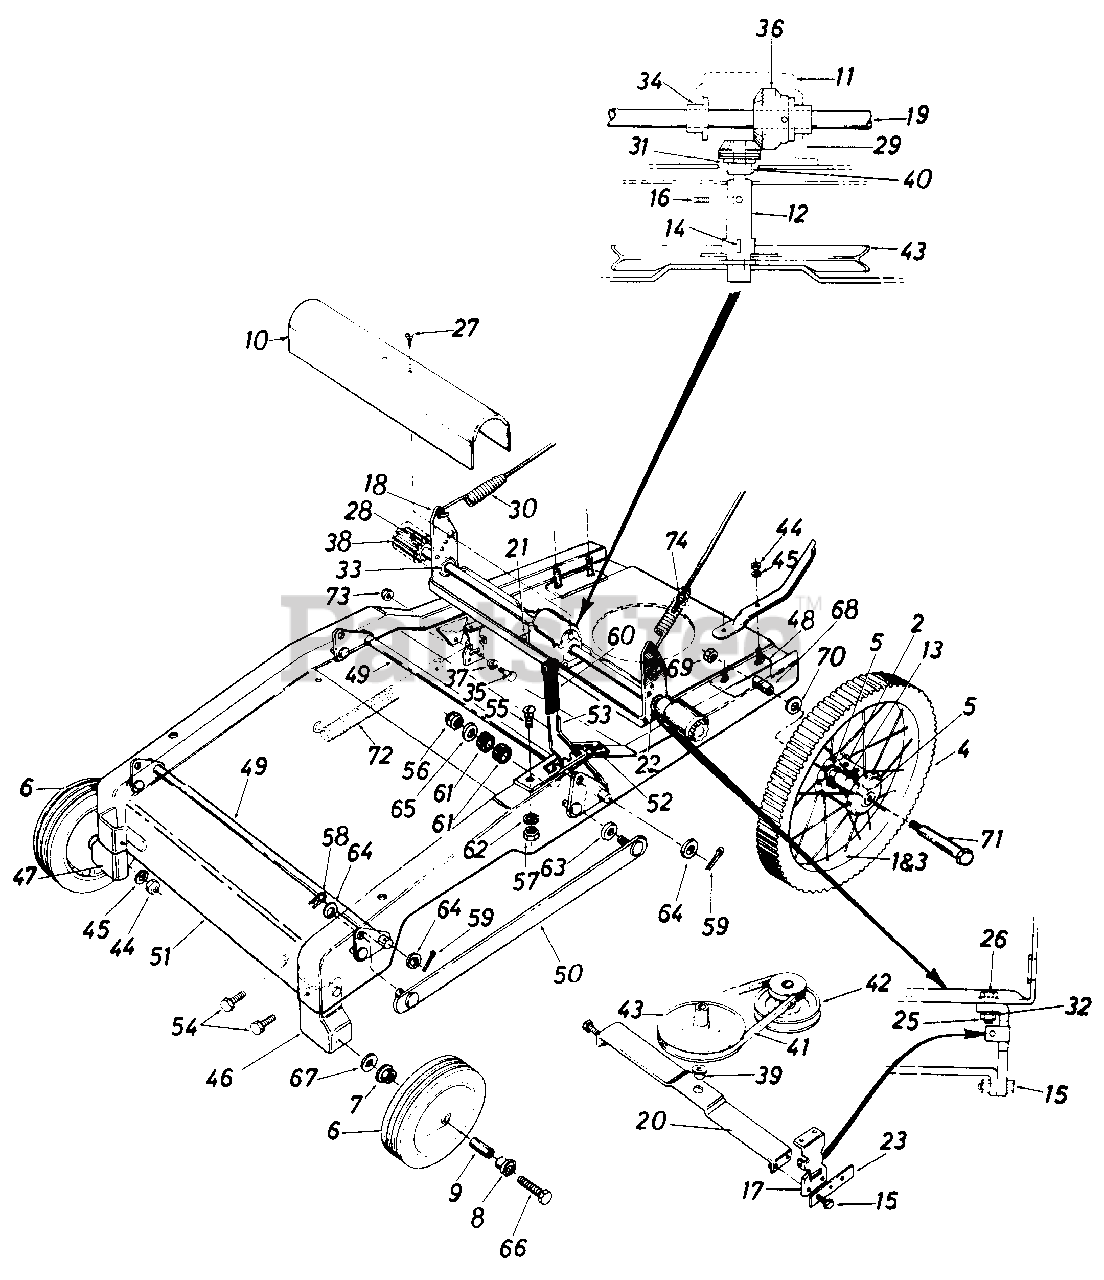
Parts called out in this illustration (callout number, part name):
1	16" Wheel Ass'y. Comp.-Rear
3	Rear Wheel Rim Only
4	Rear Wheel Tire Only 16 x 1 .75
5	Ball Brg. .630" I.D.
6	Wheel Ass'y. Comp. Front 8 x 1.75
7	Flanged Ball Brg. 3/8" I.D.
8	Flanged Ball Brg. 1/2" I.D.
9	Spacer 3/8" I.D.
10	Top Drive Frame Cover
11	Gear Box Cover
12	Pinion Ass'y.
13	Wheel Spacer
14	#2 Woodruff Key 3/32 x 1/2" Dia. Hdn.
15	Hex Sems Bolt 5/16-18 x 1.00" Lg.*
16	Set Scr. 5/16-18 x .25" Cup
17	Bottom Drive Frame
18	Top Drive Frame Ass'y.
19	Drive Shaft
20	Bottom Drive Frame Ass'y.
21	Hex Self-Tap Scr. 1/4-20 x .62" Lg.
22	Collar 5/8" I.D.
23	Drive Frame Stop
25	Hex Nut 5/16-18 Thd.*
26	Hex Sems Bolt 5/16-18 x .75" Lg.*
27	Hex Wash. Hd. AB-Tap Scr. #8 x .50" Lg.
28	Spring Pin 3/16" Dia. x 1.12" Lg.
29	Gear Box
30	Extension Spring
32	L-Wash. 5/16" I.D.*
33	Ball Brg..630" I.D.
34	Flange Brg. .630" I.D.
35	Shld. Bolt .443" Dia. x .330
36	Bevel Gear.62" I.D. 28 0 Teeth
38	Drive Pinion
39	Hex Flange Brg. .503" I.D.
40	Flange Brg. .503" I.D. w/ Groove
41	3V-Belt 28" Lg.
42	Double Pulley
43	3/8" V-Pulley .502" I.D. x 6.5" O.D.
44	Hex L-Nut 3/8-16 Thd.
45	L-Wash. 3/8" I.D.*
46	Wheel Brk't. Ass'y. L.H.
47	Wheel Brk't. Ass'y. R.H.
48	Rear Wheel Brk't. Assy.
49	Lift Bracket Shaft Ass'y.
50	Connecting Link Ass'y.
51	Frame
52	Lift Handle Support Brk't.
53	Lift Handle
54	Hex Sems Bolt 5/16-18 x .75" Lg.*
55	Carriage Bolt 5/16-18 x .62" Lg.*
56	Hex Ins. L-Nut 3/8-24 Thd.
57	Hex Nut 5/16-18 Thd.*
58	Intern. Cot. Pin 5/16" Dia.
59	Cot. Pin 1/8" Dia. x 1.00" Lg.*
61	Rubber Wash. .33" I.D. x .87" O.D.
62	L-Wash. 5/16" I.D.*
63	Fl-Wash. .406" I.D. x 1.25" O.D. x .164
64	Fl-Wash. .510" I.D. x 1.0" O.D. x .060
65	Fl-Wash. .385" I.D. x .87" O.D. x .06
66	Hex Bolt 3/8-16 x 2.00" Lg.*
67	Bell-Wash. .400" I.D. x .88" O.D.
68	Spacer.523" I.D. x .640" O.D. x 1.955
69	Hex Top L-Nut 3/8-16 Thd.
70	Fl-Wash. .531" I.D. x .93" O.D.
71	Shld. Bolt .498" Dia. x 4.755
72	Extension Spring .56" O.D. x 8.25" Lg.
73	Hex Ins. L-Nut 5/16-18 Thd.
74	Hex Ins. L-Nut 1/4-20 Thd.
